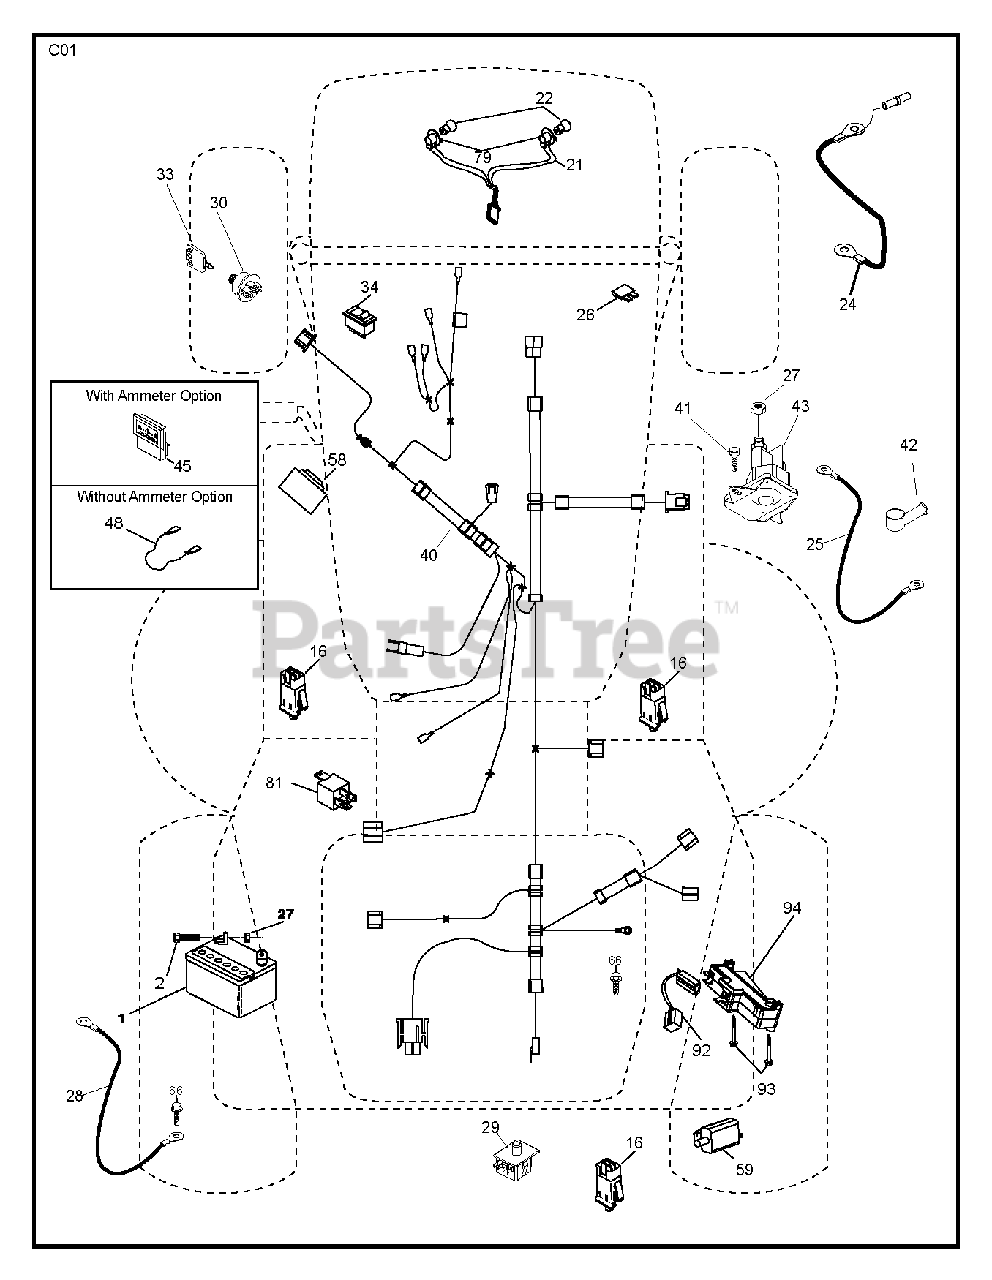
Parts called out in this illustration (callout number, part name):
1	REPL BY 532 12 38-99
16	SWITCH INTERLOOK PUSH-IN
21	HARNESS ASSY LIGHT
22	LIGHTBULB
24	CABLE BATTERY
25	CABLE BATTERY 6 GA. 11" RED
26	FUSE 20AMP
27	NUT
28	CABLE GROUND
29	SWITCH.SEAT.DP W/RAMPS
30	SWITCH.IGN.DELTA.W.LGH.ROS
33	KEY.CHAIN.BLISTER.PACK.GEN.INT
34	SWITCH LT
42	TERMINAL COVER
43	SOLENOID.W/BRASS.PLUNG
58	BUZZER
79	BULB HOLDER ASM.
81	RELAY.ASSY.T
92	HARNESS.PIGTAIL.CONSLE
93	SCREW.PLASTITE
94	MODULE.REVERSE.ROS
